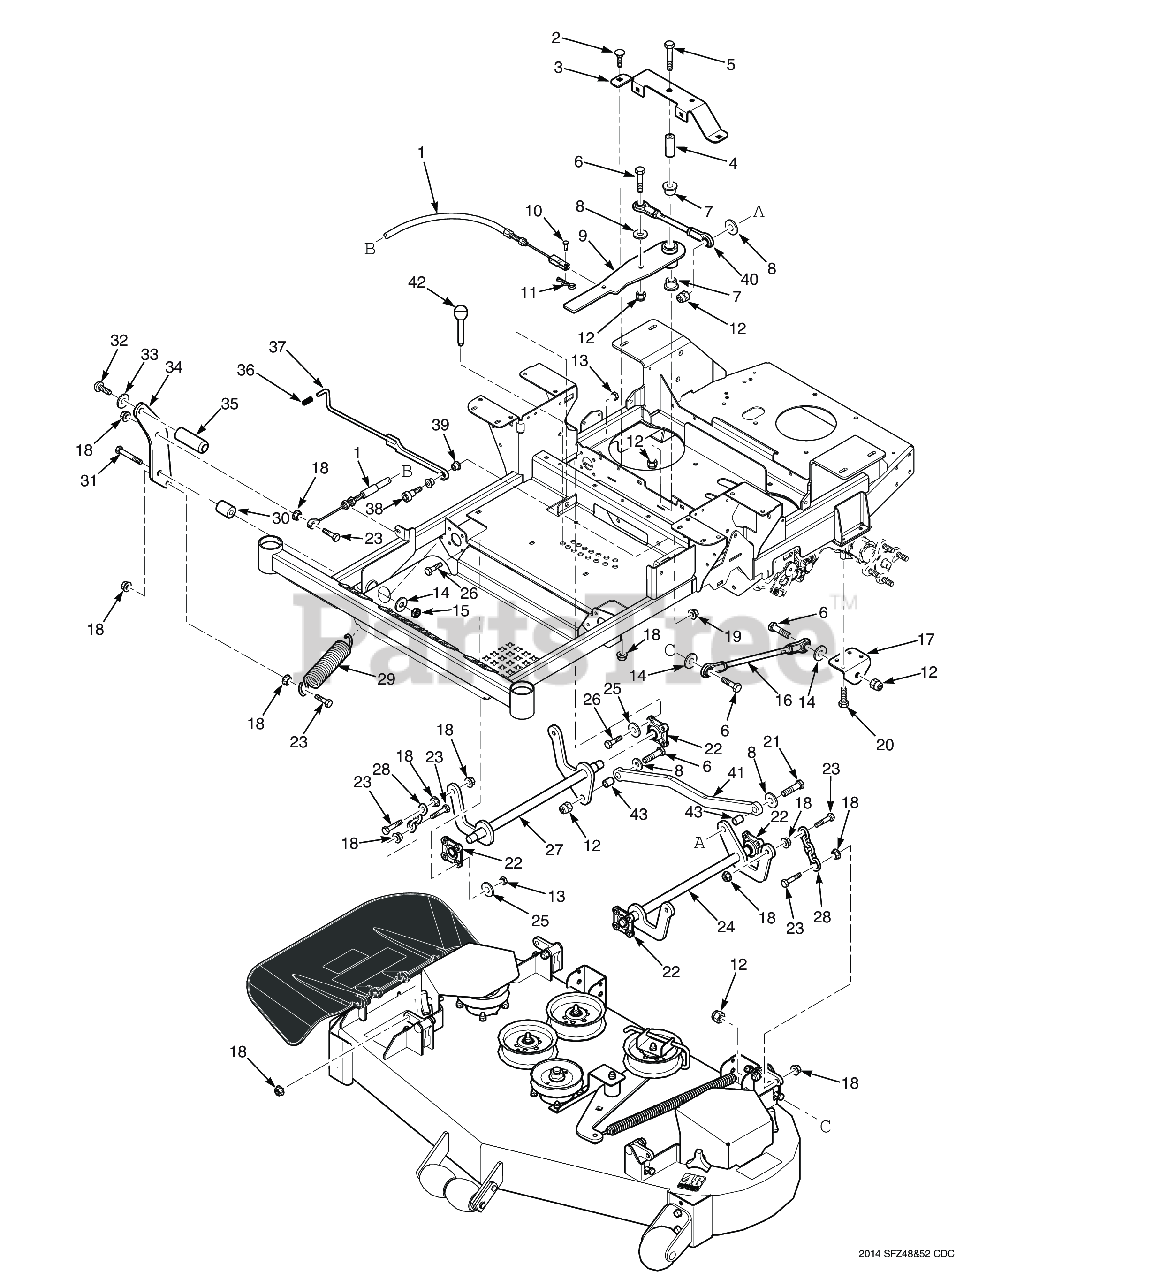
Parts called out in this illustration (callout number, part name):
1	Cable, Deck Lift
2	Bolt, Carriage 3/8-16 x 3/4"
3	Support, Idler Arm
4	Spacer, Deck Lift Pivot
5	Bolt, Hex Head, 1/2-13 x 3-1/4"
6	Hex Head Bolt, 1/2-13 x 2"
7	Bearing, Plastic
8	Flatwasher, 1/2 - .531 x 1.062 x .095
9	Deck Lift Bellcrank Assembly
10	Clevis Pin, 5/16 x 3/4"
11	COTTER PIN, HAIR - 0.94 X 1.62
12	HEX LOCKNUT, ELASTIC STOP, 1/2-13
13	HEX NUT, ELASTIC STOP LOCK, 5/16-18
14	Flat Washer, 1/2 (.562 x 1.375 x .109)
15	HEX NUT, ELASTIC STOP LOCK, 3/8-16
16	Linkage, Push Arm
17	Bracket, Push Arm Link
18	NUT, 3/8-16 SERRATED FLANGE HEX HEAD
19	HEX NUT, ELASTIC STOP LOCK, 3/8-16
20	Bolt, Hex Head 5/16-18 x 3.00"
21	Bolt, Hex Head 1/2-13 x 2-3/4" (48V & 52V - One Weight)
22	Bearing, Deck Lift - 48V & 52V
23	Bolt, Hex Head, 3/8-16 x 1-1/2"
24	Weldment, Deck Lift LH
25	Flatwasher, 1/4" (.312 x .750 x .065")
26	Bolt, Heax Head 5/16-18 x 1" (48V / 52V)
27	Weldment, Deck Lift RH
28	Chain, Deck Lift
29	Spring, Deck Lift
30	Spacer, Deck Lift Pivot
31	Bolt, Hex Head 1/2-13 x 3"
32	Bolt, Head Socket 5/8-11 x 1-1/2"
33	Lockwasher, 5/8" Spring
34	Pedal, Foot Bracket
35	Foot Pedal, Height Adjustment
36	Grip, Deck Latch
37	Weldment, Deck Latch
38	Bolt, Shoulder 1/2 x 1/2"
39	Bearing
40	Linkage Assembly, Deck Lift
41	Mounting Bracket, Fuel Tank Front
42	Pin, Height Adjuster
43	Sleeve
